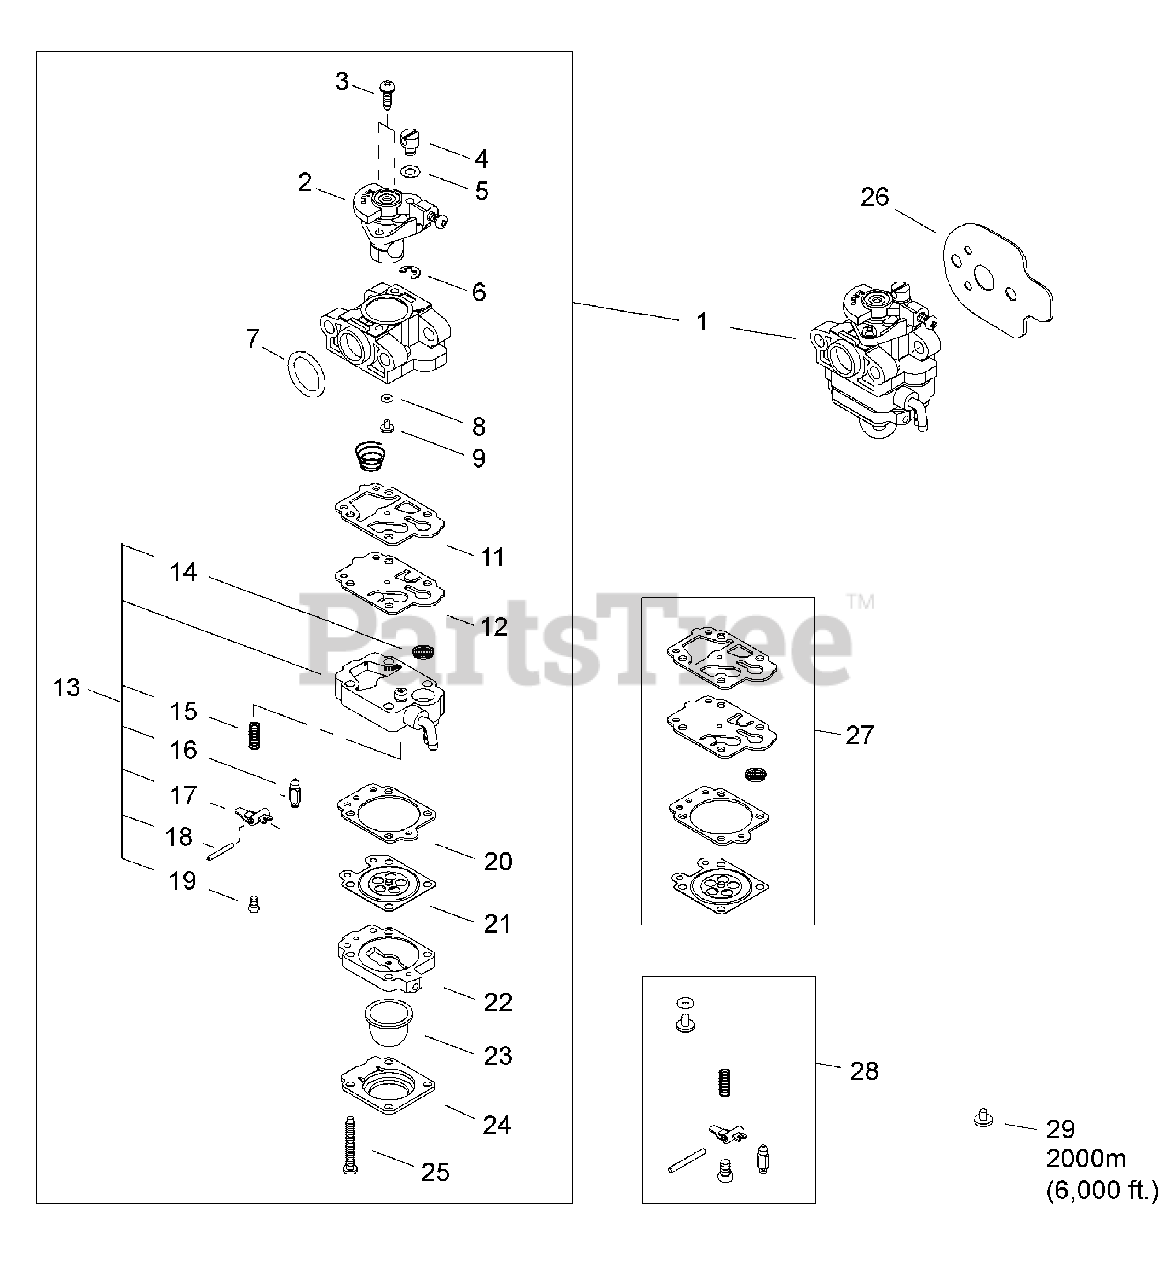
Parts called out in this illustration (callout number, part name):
1	CARBURETOR
2	VALVE ASSY, THROTTLE
3	SCREW, THROTTLE COLLAR
4	SWIVEL
5	WASHER
6	E-RING
7	O-RING 15
8	O-RING
9	JET, MAIN
11	GASKET, PUMP
12	DIAPHRAGM, PUMP
13	BODY ASSY, PUMP
14	SCREEN, FUEL INLET
15	SPRING, METERING LEVER
16	VALVE, INLET NEEDLE
17	LEVER, METERING
18	PIN, METERING LEVER
19	SCREW
20	GASKET, METERING DIAPHRAGM
21	DIAPHRAGM, METERING
22	BODY ASSY, PURGE
23	BULB, PURGE
24	RETAINER, PURGE BULB
25	SCREW
26	GASKET, INTAKE
27	GASKET / DIAPHRAGM KIT
28	SWITCH, ON-OFF
29	JET, MAIN
